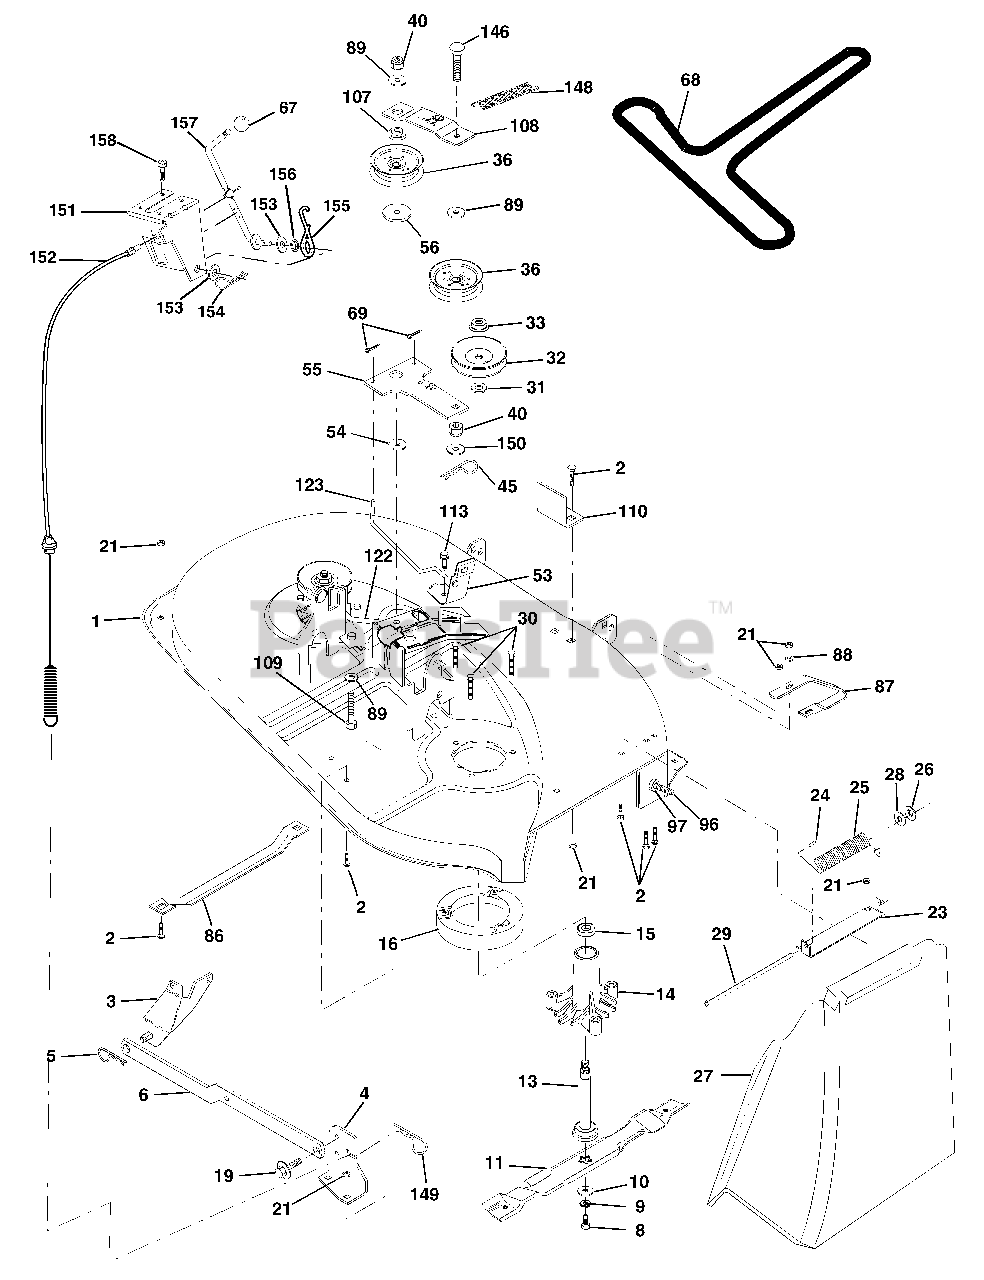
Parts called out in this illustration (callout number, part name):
1	Mower Housing Assembly
2	Bolt Carriage 5/16-18 x 3/4
3	Bracket Asm Fr. Sway Bar
4	Bracket Deck Sway Bar 38"/42"
5	Retainer Spring
6	Bar Sway Deck
8	Bolt 3/8-24 x 1.25 Grade 8
9	Washer, Lock 3/8
10	Washer, Hardened
11	Blade, 38" Mulching Std
11	Blade, 38" Mulching Premium
11	Blade, 38" Hi-Lift
13	Shaft Assembly, Mandrel, Vented
14	Housing, Mandrel, Vented
15	Bearing, Ball, Mandrel
16	Stripper, Vented Mower Deck
19	Bolt, Shoulder
21	Nut
23	Bracket, Mower Deflector
24	Cap, Sleeve
25	Spring, Torsion, Deflector
26	Nut, Push
27	Shield, Deflector
28	Washer 11/32 x 5/8 x 16 Gauge
29	Rod, Hinge
30	Screw Thdrol. Washer Head
31	Washer, Spacer
32	Pulley, Mandrel
33	Nut, Toplock
36	Pulley, Idler, Flat
40	Nut, Crownlock 3/8-16 Unc
45	Retainer
53	Brake Assembly
54	Washer, Hardened
55	Idler Arm Assembly
56	Spacer, Retainer
67	Knob
68	V-Belt, 42" Mower
69	Pin, Cotter 3/32 x 3/4
86	Runner, LH
87	Runner, RH
88	Washer 11/32 x 3/4 x 16 Ga
89	Washer 13/32 x 1 x 12 Ga.
96	Bolt 3/8-16 x 1-1/4 Mulcher
97	Nut Centerlock 3/8-16 Unc
107	Spacer Retainer
108	Stiffener, Idler Arm
109	Bolt, Hex Hd 3/8-16 x 2-1/2
110	Upstop Deck Front 38"
113	Screw 5/16-1/ x 3/4
122	Rod, Brake LH
123	Rod, Brake RH
146	Bolt Carriage Idler
148	Spring Return Idler
149	Retainer Spring Yellow
150	Washer 9/32 x 3/4 x 16 Ga.
151	Bracket Clutch Cable
152	Clutch Cable 38"/46"
153	Washer Flat 3/8" Type B
154	Spring Retainer
155	Spring Retention LVR CLTCH CAB
156	Spacer Clutch Cable
157	Rod Clutch Cable 3/8"
158	Screw Hex Thd Cut 1/4-20 x 1/2
